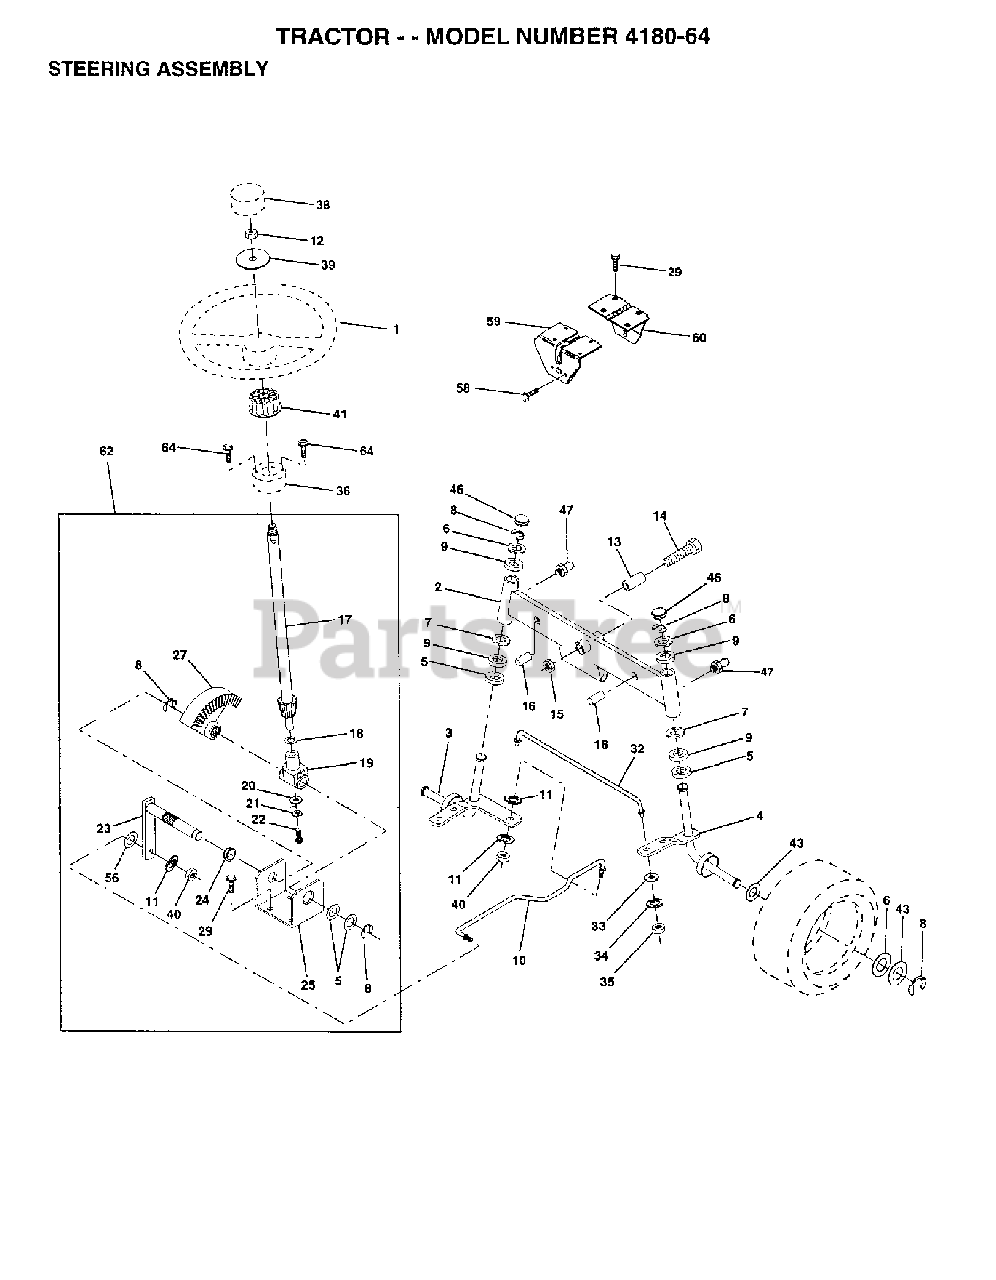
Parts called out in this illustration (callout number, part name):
1	Steering Wheel
2	AXLE ASSY
5	WASHER THRUST
8	RING CLIP
9	BEARING.STEERING.COLUMN
10	DRAG LINK
11	WASHER, LOCK 3/8
12	NUT.HEX.1/2-20
15	LOCK NUT
17	SHAFT ASS'Y STEER
18	THRUST WASHER
19	SHAFT,SUPPORT
20	WASHER
21	LOCKWASHER
22	SCREW
23	SHAFT,PITMAN
24	NYLINER T (7283A)
25	BRKT,STEERING
27	GEAR.SECTOR
33	WASHER M
34	LOCKWASHER
35	LOCKNUT
36	BUSHING STRG 3/4
38	INSERT STR WHL
40	NUT
46	CAP.SPINDLE.BLACK
47	ZERK.GREASE.TAPERED
56	WASHER
58	SCREW LT
59	SUPPORT-SADDLE LT NLA
60	SUP-SADDLE FRT LT
62	KIT-STEERING
64	SCREW.TT.#10-32X.5.3/8.FLANGE
